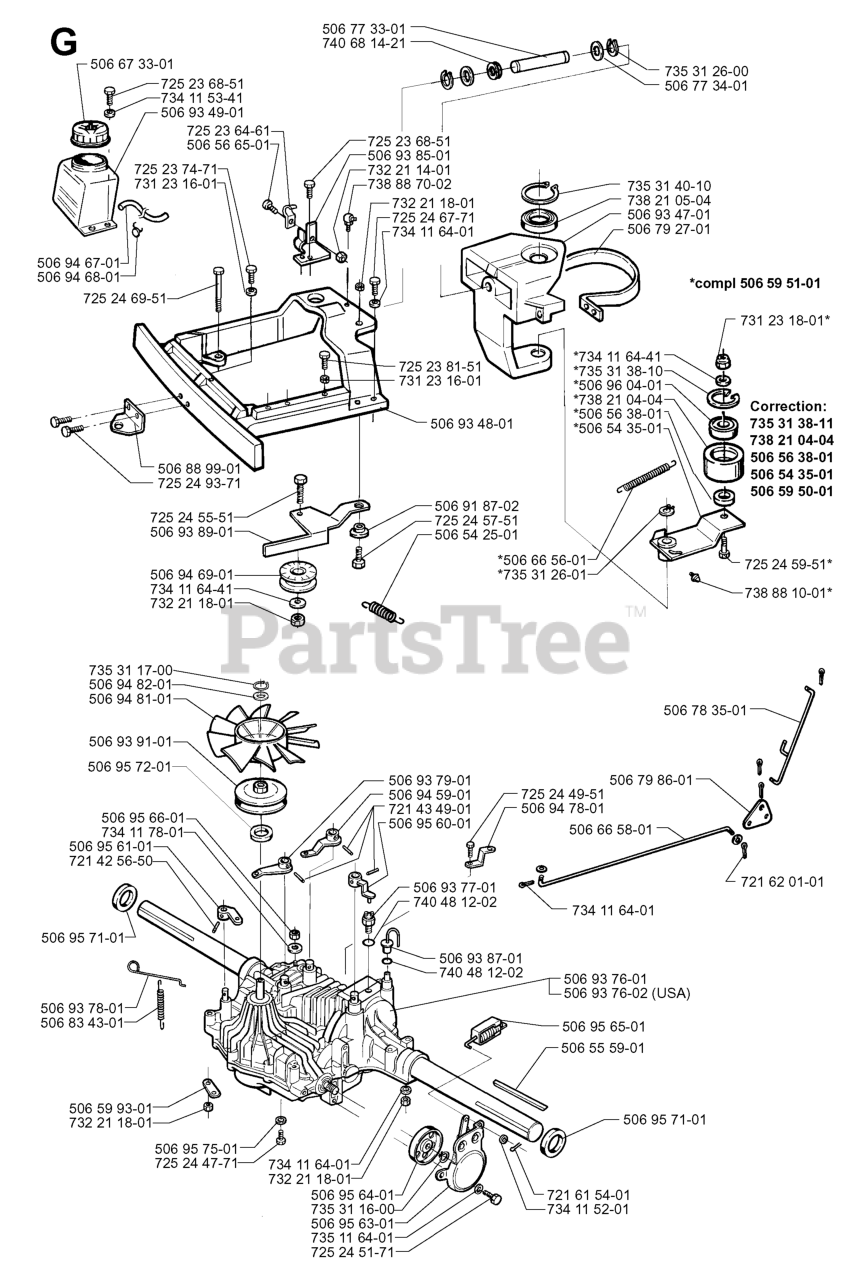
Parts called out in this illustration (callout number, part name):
1	TRANSAXLE, TUFFTORQ K46
2	SQUARE KEY
15	WASHER
17	SPRING.BRAKE.K46.GREEN
26	SPRING.RETURN.CRUISE
29	ROD.BRAKE.K46
35	ROD.BRAKE.PARKING.GT.H
42	PEDAL COVER T
50	IDLER.FLAT.910.OFFSET
51	NUT LOCK FLG 3/8-16 UNC
52	IDLER.V-GROOVE.910.OFFSET
56	V-BELT.MOWER.92.40.42/K46
64	SHAFT.ASM.PEDAL.BRK.CNTR
73	BOLT HEX 5/16-18 GR 5
80	STRAP TORQUE.ASM.K46/18"TEX
92	BOLT
99	ROD.SPRING.BYPASS.K46.LT.Z
116	NUT LOCK HEX FLANGE 5/16-18
125	SCREW
143	Screw 5/16-18 x 1/2 Hex, Self Tapping 5/16-18 x 1/2
153	RETAINER M
159	COTTER PIN
160	RETAINER CLIP
161	SPRING, RETURN LT
163	ROD.CONTROL.PEDAL.K46
166	NUT.PUSH.625.2006
167	LATCH.BRAKE.SPRING
170	KEEPER.V-IDLER.CENTER.
183	SPACER AXLE
184	HANDLE.PARKG.BRK.HUSQ X667
186	SPACER.RETAINER
187	WASHER 12/32X2X10GA
188	RP.LINK.CLUTCH.GROUND.DRIVE
189	BELLCRANK.GROUND.DRIVE.TEX.
190	KEEPER.BELLCRANK.DRIVE
196	SCREW 3/8-16X1
197	LINK.CLUTCH.ANIT-ROTAT
206	BRKT.MOUNT.LATCH.CRUIS
207	LATCH.CONTROL.CRUISE
208	GEAR.SECTOR.CONTROL.CR
209	ROD.CONTROL.CRUISE.GT.
210	ROCKER.ASM.PEDAL.CONTR
211	BEARING.NYLON
213	KNOB.CONTROL.CRUSIE.HU
214	PEDAL.FORWARD.HUSQVARNA.DEALER
215	PEDAL.REVERSE.TEX.GT.4
216	BRACKET.PULLEY.IDLER.W/TEX
221	RETAINER.SPRING.CLIP.H
222	WASHER 21/32 X 1-1/4 X 10 GA.
225	KEEPER.BELT.TRANSAXLE.K46
226	BRACKET.MOUNT.TORQUE.K46.TLT
230	WASHER.HARDENED
284	NUT.U-CHNL.1/4-20.550DP.350PNL
285	SCREW.PHD.1/4-20.BOX DRVE
